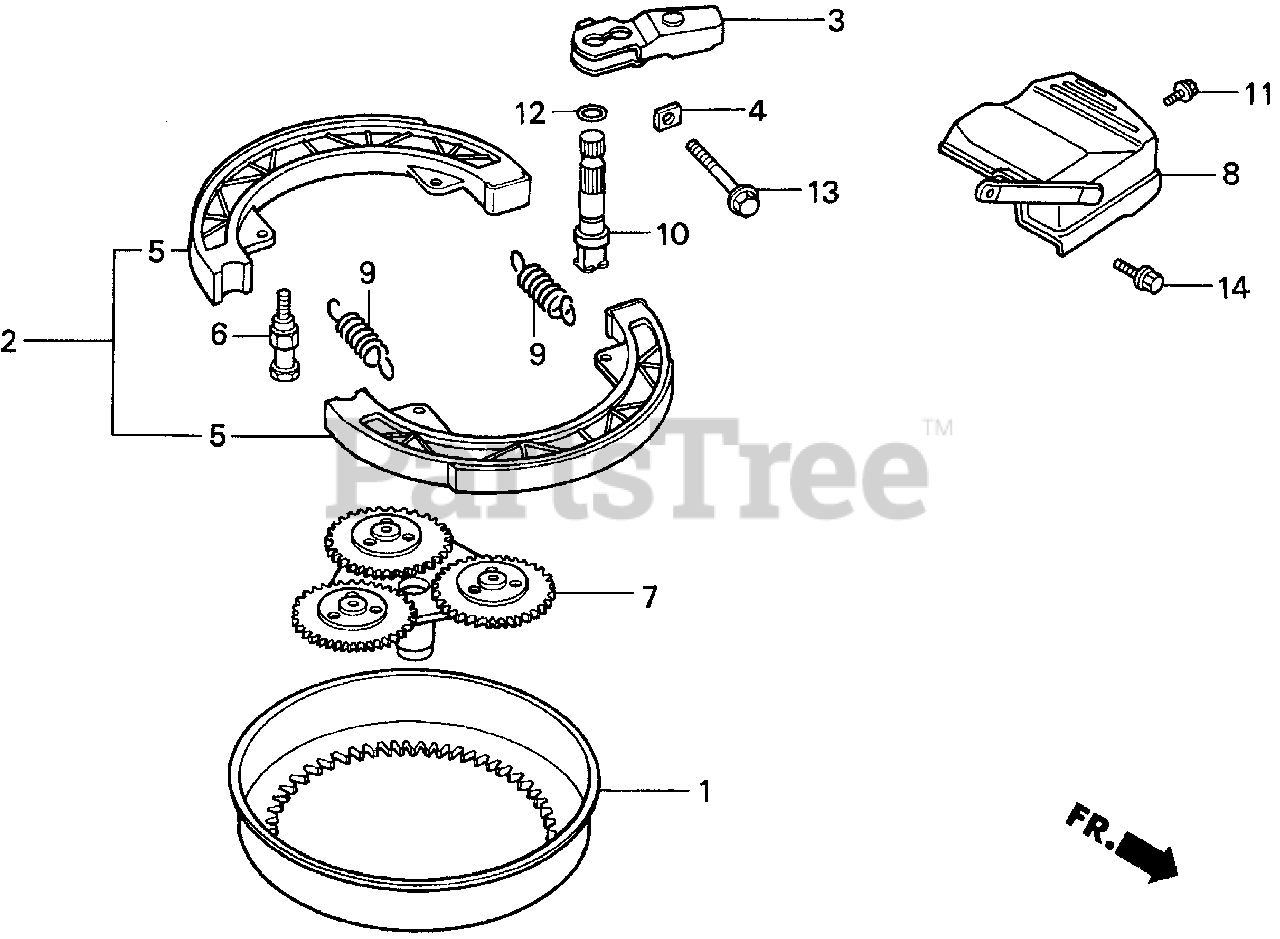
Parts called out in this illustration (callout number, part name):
1	CLUTCH (OUTER)
2	SHOE SET, CLUTCH
3	ARM, CLUTCH
4	PLATE, ARM LOCK
6	PIN, ANCHOR
7	PLATE, DRIVE
8	COVER, CLUTCH ARM
9	SPRING, FR. BRAKE SHOE
10	CAM, CLUTCH
11	BOLT, FLANGE (6X12) (CT200)
12	O-RING (8.8X1.9)
13	BOLT, FLANGE (6X32)
14	BOLT, FLANGE (8X16)
